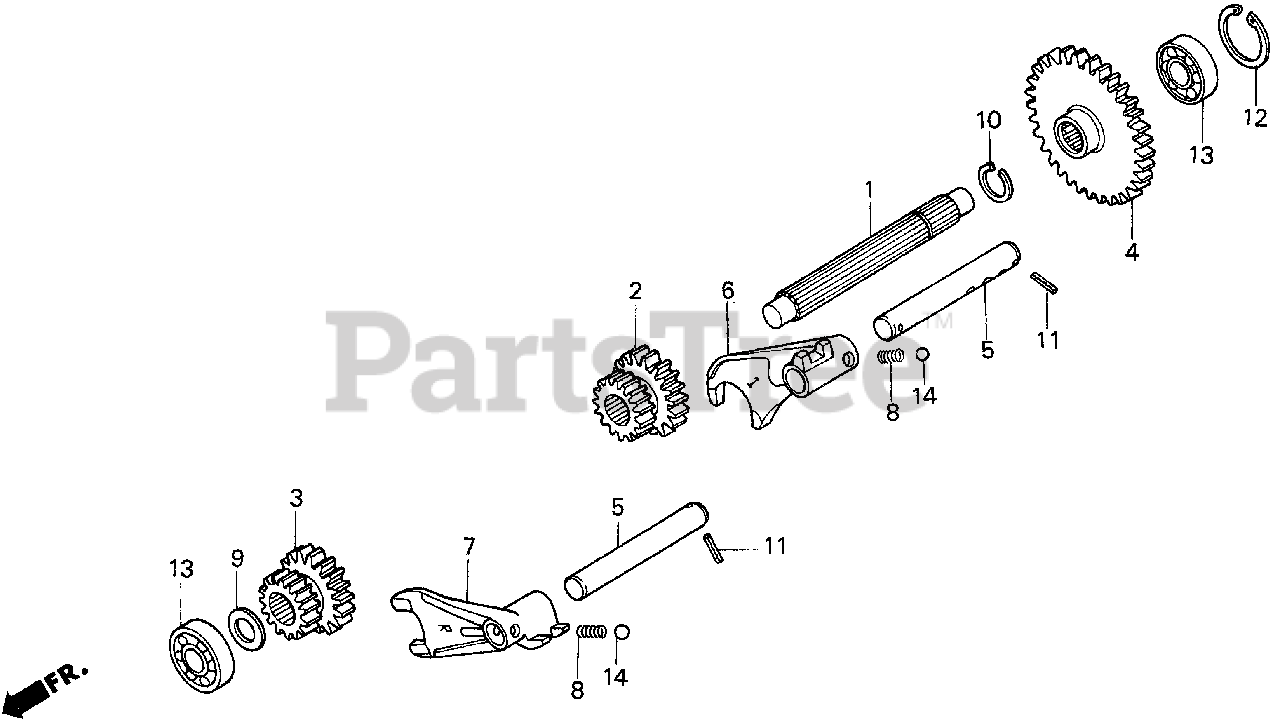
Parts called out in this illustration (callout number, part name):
1	COUNTERSHAFT (UPPER)
2	GEAR, FIRST-SECOND CHANGE (27T-17T)
3	GEAR, REVERSE CHANGE (27T-17T)
4	GEAR, COUNTERSHAFT (53T)
5	SHAFT, MAIN CHANGE
6	FORK, SHIFT (1-2)
7	FORK, REVERSE SHIFT
8	SPRING A, BALL SETTING
9	WASHER (17MM)
10	CIRCLIP (OUTER) (20MM)
11	PIN, SPRING (3X18)
12	CIRCLIP (INNER) (40MM)
13	BEARING, RADIAL BALL (6203)
14	BALL, STEEL (#10) (5/16)
